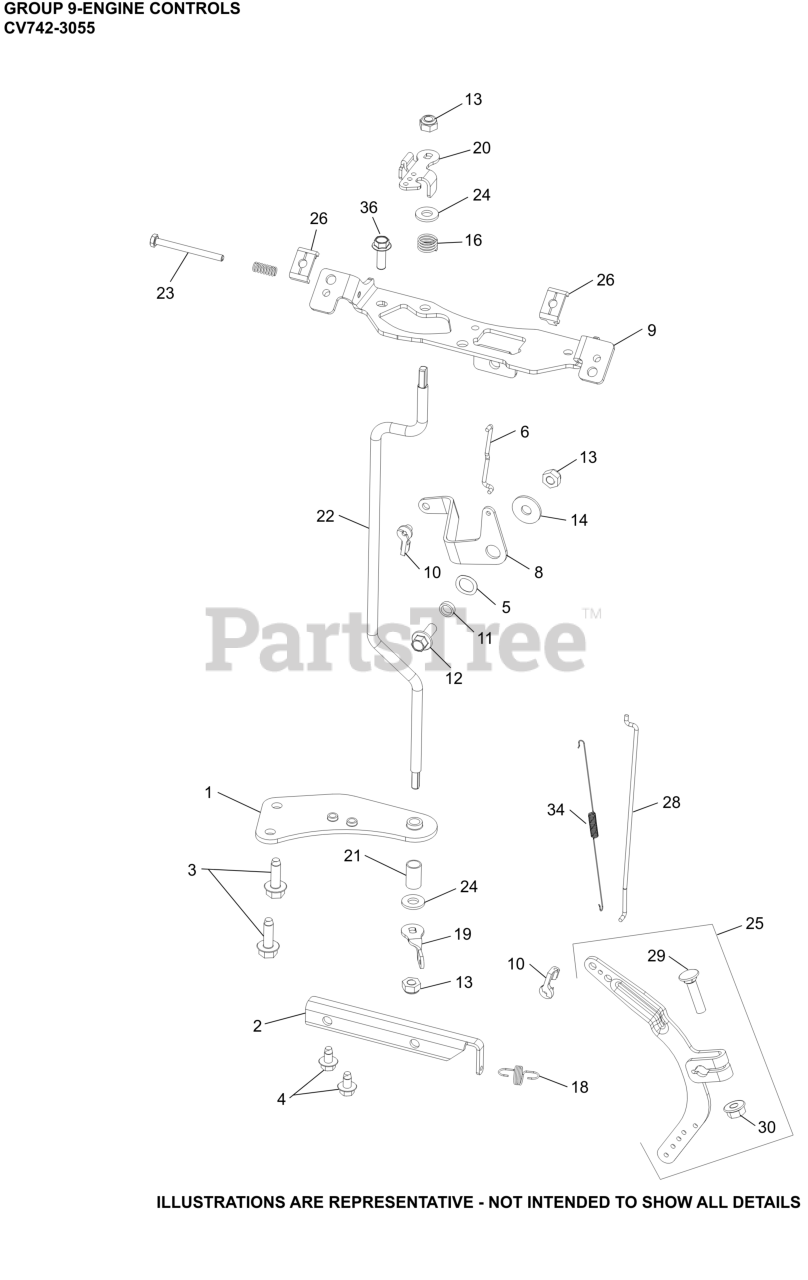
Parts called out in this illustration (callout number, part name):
1	BRACKET, THROTTLE SHAFT
2	BRACKET, GOVERNED IDLE
3	SCREW, THREAD FORMING
4	SCREW, THREAD FORMING
5	WASHER, SPRING 3/8"
6	LINKAGE, CHOKE
8	LEVER, CHOKE
9	BRACKET, CONTROL
10	BUSHING, THROTTLE LINKAGE
12	SCREW, FLG M6X1.0X16
13	NUT, LOCK M6X1.0
14	WASHER, FLAT 1/4"
16	SPRING, THROTTLE SHAFT
18	SPRING, GOVERNOR (GREEN)
18	SPRING, GOVERNED IDLE
19	LEVER, THROTTLE CONTROL
20	LEVER, THROTTLE CONTROL
22	SHAFT,CONTROL
23	SCREW, HEX HEAD
24	WASHER, FLAT 1/4"
25	LEVER, GOVERNOR - (#2409069S)
25	LEVER, GOVERNOR ASSEMBLY
26	CLAMP, CABLE
28	LINKAGE, THROTTLE
29	BOLT, RD HD SQ NECK M6X1.0X25
30	NUT, FLG M6X1.0
34	SPRING, LINKAGE
36	SCREW, HI-LOW
